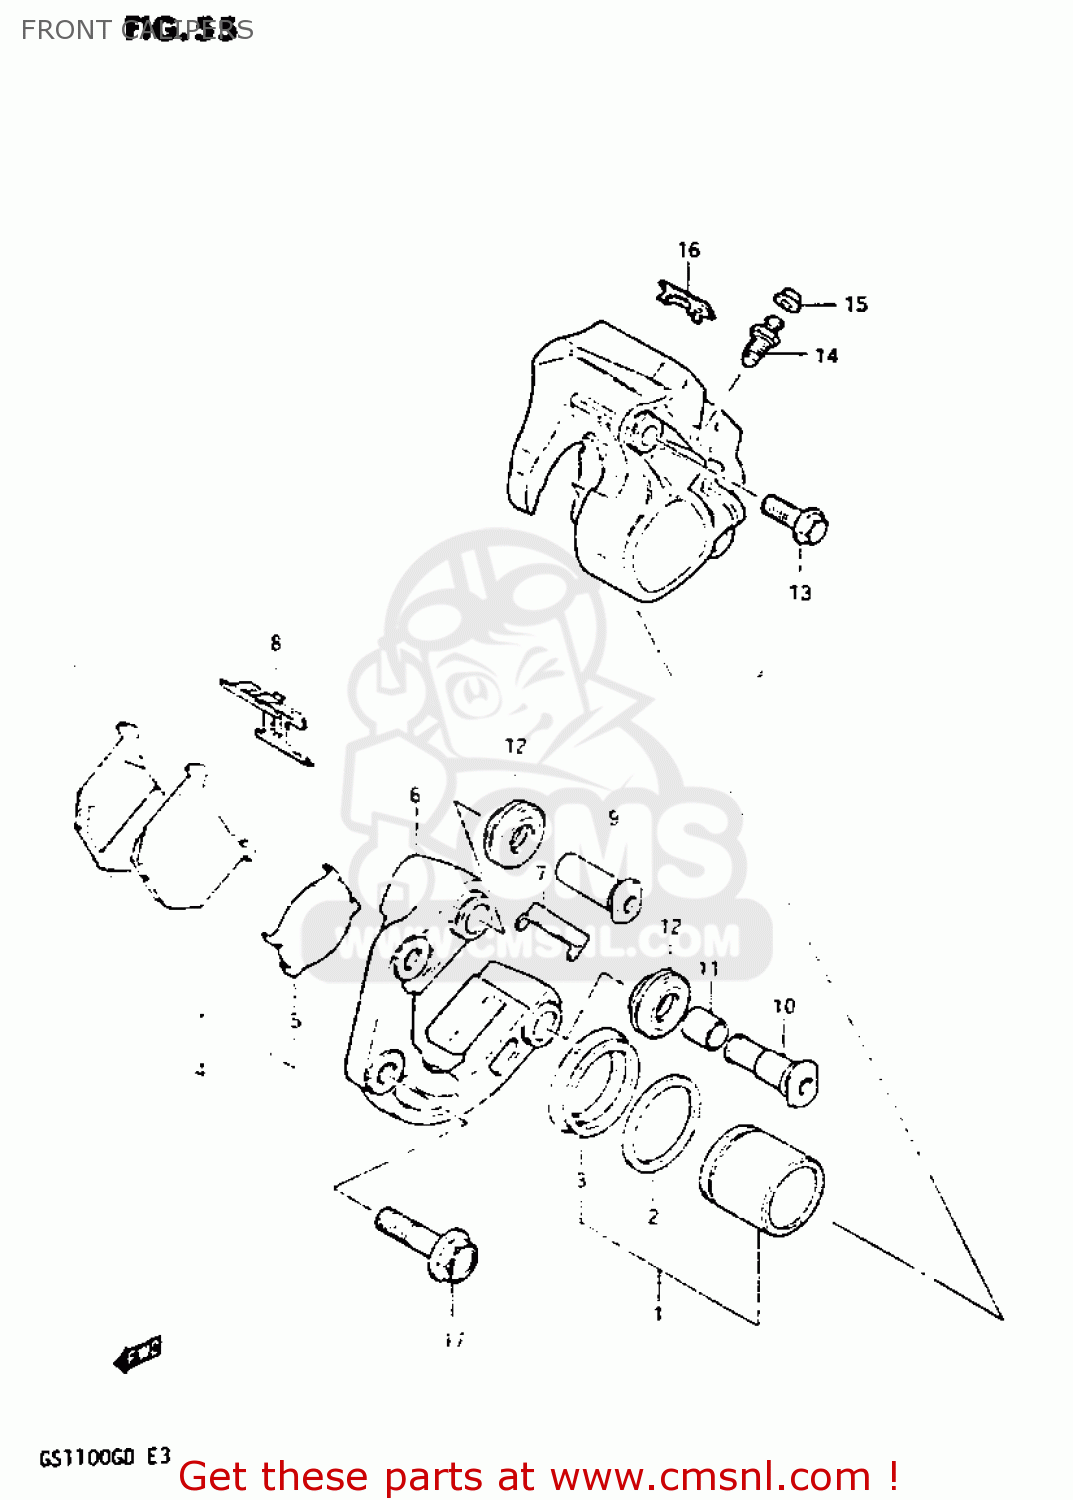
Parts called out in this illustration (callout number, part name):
1	PISTON SET
2	SEAL,PISTON
3	BOOT,PISTON
4	PAD SET,BRAKE (MCA)
5	SHIM,PAD
6	CARRIER,CALIPER,LEFT
7	GUIDE,PAD
8	SPRING,PAD
9	AXLE NO.1
10	AXLE NO.2
11	BUSH,AXLE
12	BOOT,AXLE
13	BOLT
14	BLEEDER
15	CAP,BREATHER
16	COVER
17	BOLT(10X37)
